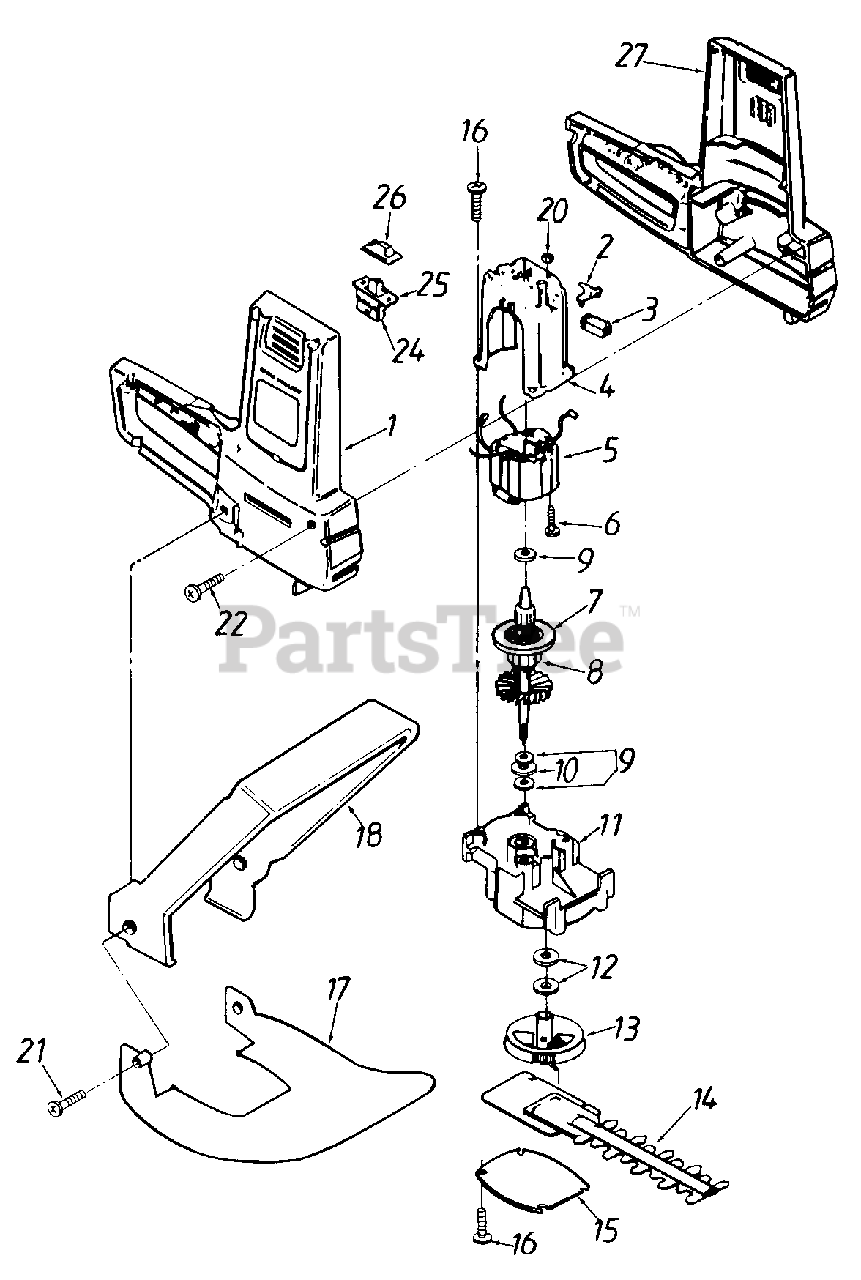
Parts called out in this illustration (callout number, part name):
1	Motor Housing Cover
3	Brush HolderAss'y.
4	Motor Housing
5	Field Ass'y.
6	Screw #8-32 x 1.125" Lg.
7	Fan Baffle
8	Armature Ass'y.
9	Fl-Wash. .316" I.D. x .5" O.D.
10	Spr.-Wash. .322" I.D. x .49" O.D.
11	Gear Box Ass'y.
12	Thrust Wash. .385" I.D. x .562"
13	Gear Ass'y
14	Blade Ass'y.
15	Cover Plate
16	Hex Wash. Hd. Tap Scr. #8-32 x 1/2" Lg.
17	Shield
18	Handle
20	Hex Top L-Nut #8-32 Thd.
21	Truss Mach. Scr. 1/4-20 x 1.125" Lg.
22	Screw #8-18x 1" Lg.
24	Insulator
25	Switch
26	Switch Cover
27	Motor Housing Support
